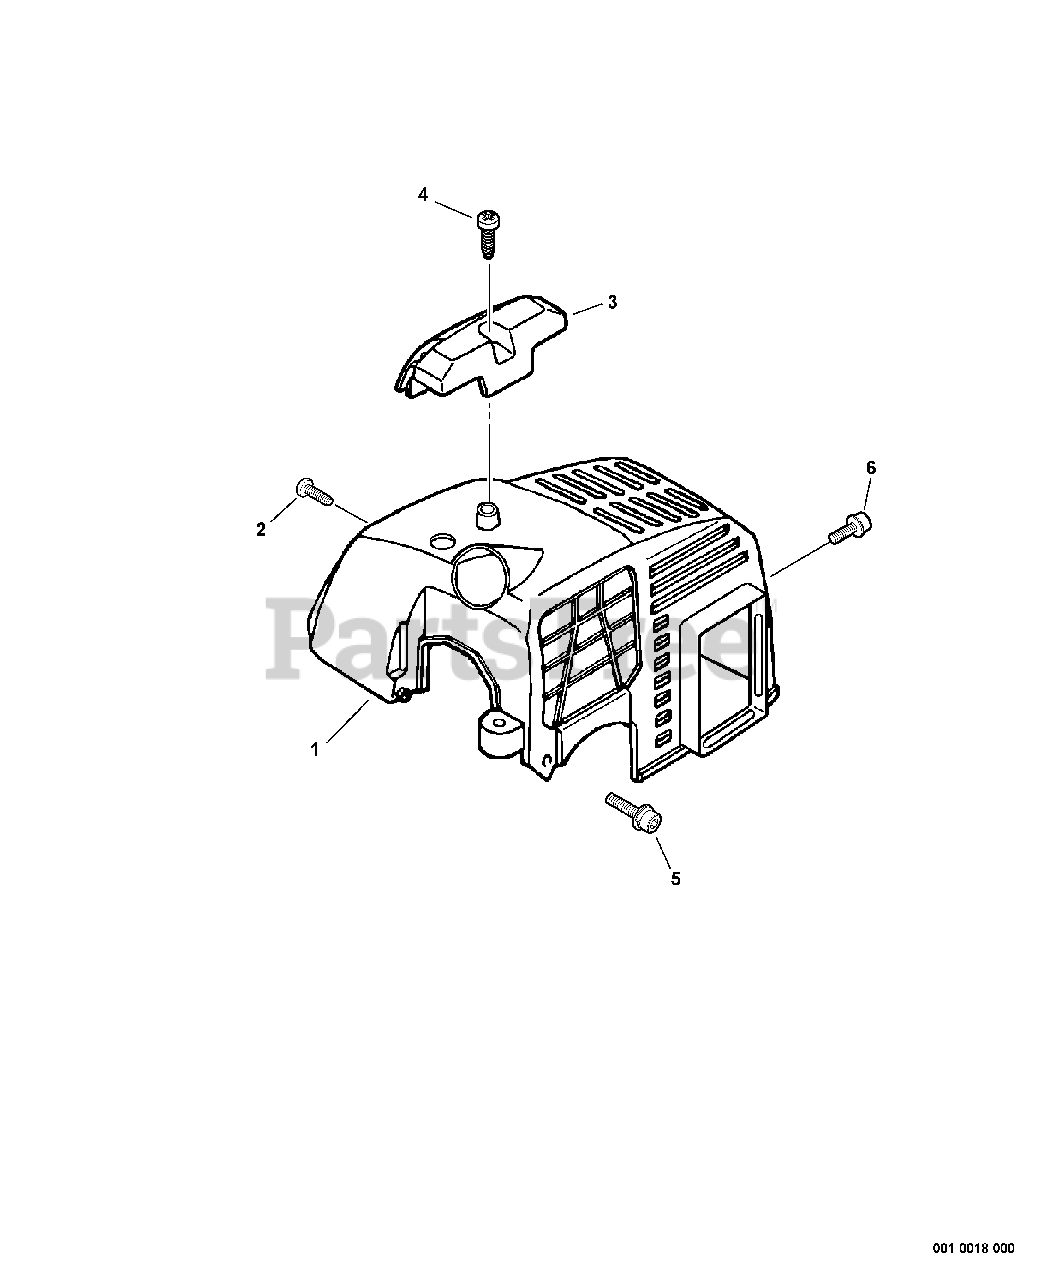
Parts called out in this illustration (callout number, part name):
1	COVER, ENGINE
2	SCREW - 4X12
3	GUARD - TOP
4	SCREW - 5X16 -- TAPPING
5	SCREW - 4X16
6	SCREW - 4X8
